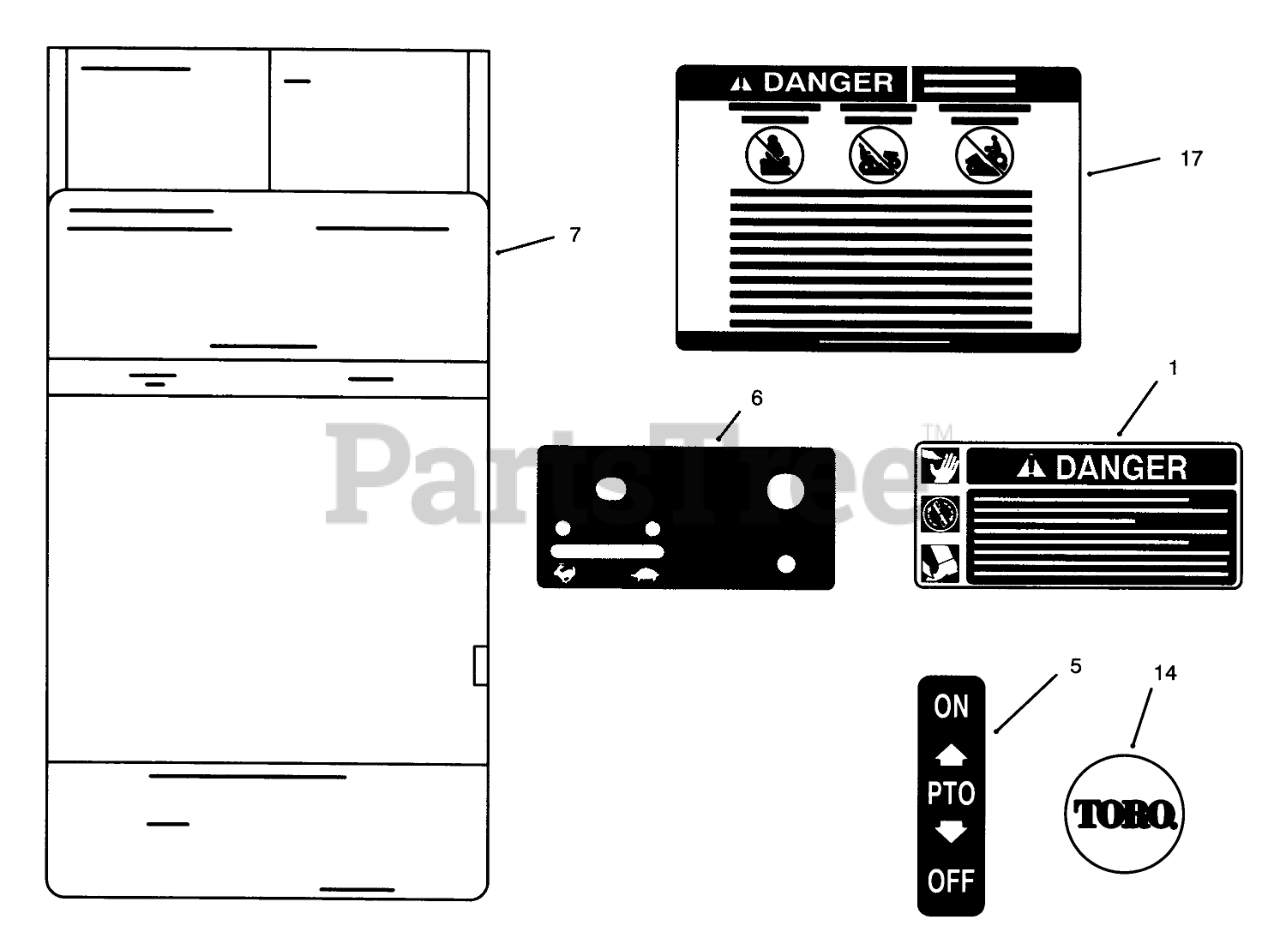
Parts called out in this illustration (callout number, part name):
1	DECAL-DANGER
5	DECAL-PTO
6	DECAL-CONTROL
7	MAINTENANCE-DECAL
14	NAME-PLATE TORO LOGO
17	DECAL-DANGER
